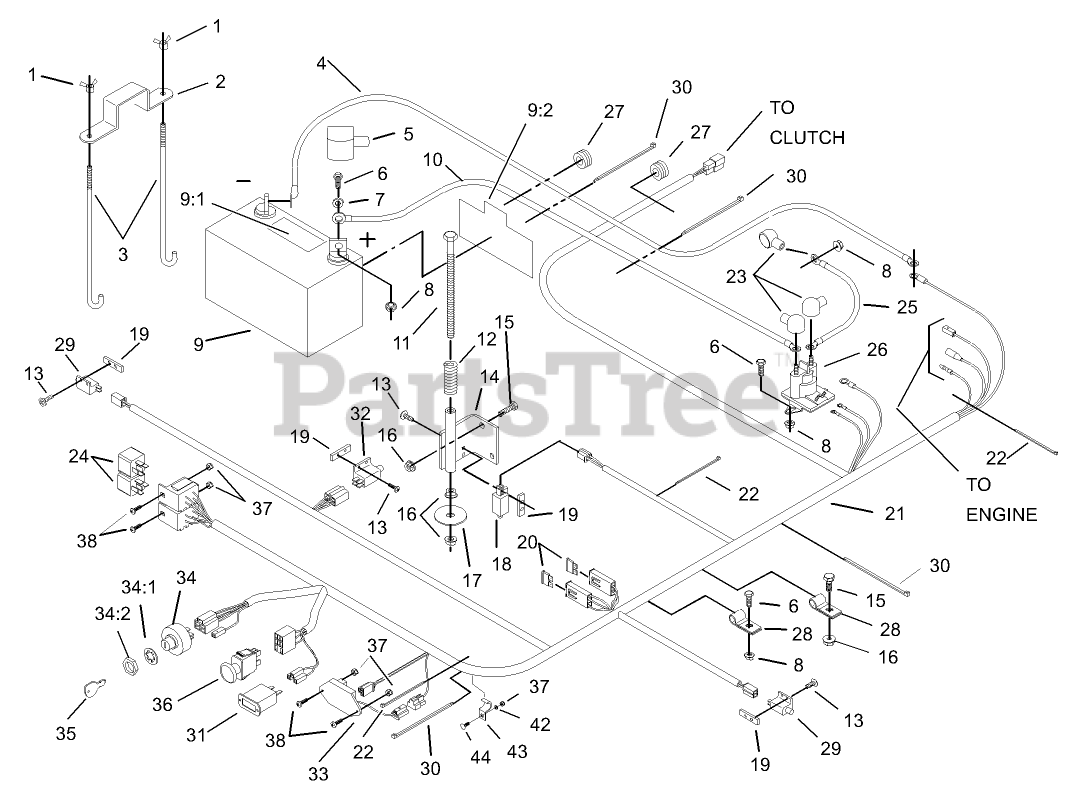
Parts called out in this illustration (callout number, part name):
1	WINGNUT
2	STRAP-HOLDDOWN
3	BOLT-HOLDDOWN
4	CABLE-GROUND, NEGATIVE
5	INSULATOR-BATTERY
6	SCREW-HH
7	WASHER-FLAT
8	NUT-HF
9	BATTERY
9:1	Decal-Battery
9:2	Decal-Battery
10	CABLE-BATTERY, POSITIVE
11	SCREW-HH
12	SPRING-SWITCH, SEAT
13	SCREW-PPH
14	BRACKET-SWITCH, SEAT
15	SCREW-HH
16	NUT-HF
17	WASHER
18	SWITCH-CLOSED, NORMALLY
19	PLATE-TAPPED
20	FUSE-BLADE TYPE, 20 AMP
21	HARNESS-WIRE
22	TIE-CABLE
23	INSULATOR-SOLENOID
25	CABLE-STARTER, POSITIVE
26	SWITCH-SOLENOID
27	GROMMET
28	CLIP-LOOM
29	SWITCH-OPEN, NORMALLY
30	TIE-PLASTIC
31	METER-HOUR
32	SWITCH
33	MODULE-DELAY, SEAT
34	Key Switch ASM
34:1	WASHER-TOOTH, INTERNAL
34:2	NUT-HH
35	KEY-IGNITION
36	SWITCH-DELTA
37	NUT-LOCK, NI
38	BOLT-CARR
42	WASHER-FLAT
43	CLIP-HALF, LOOM
44	BOLT-CARR
